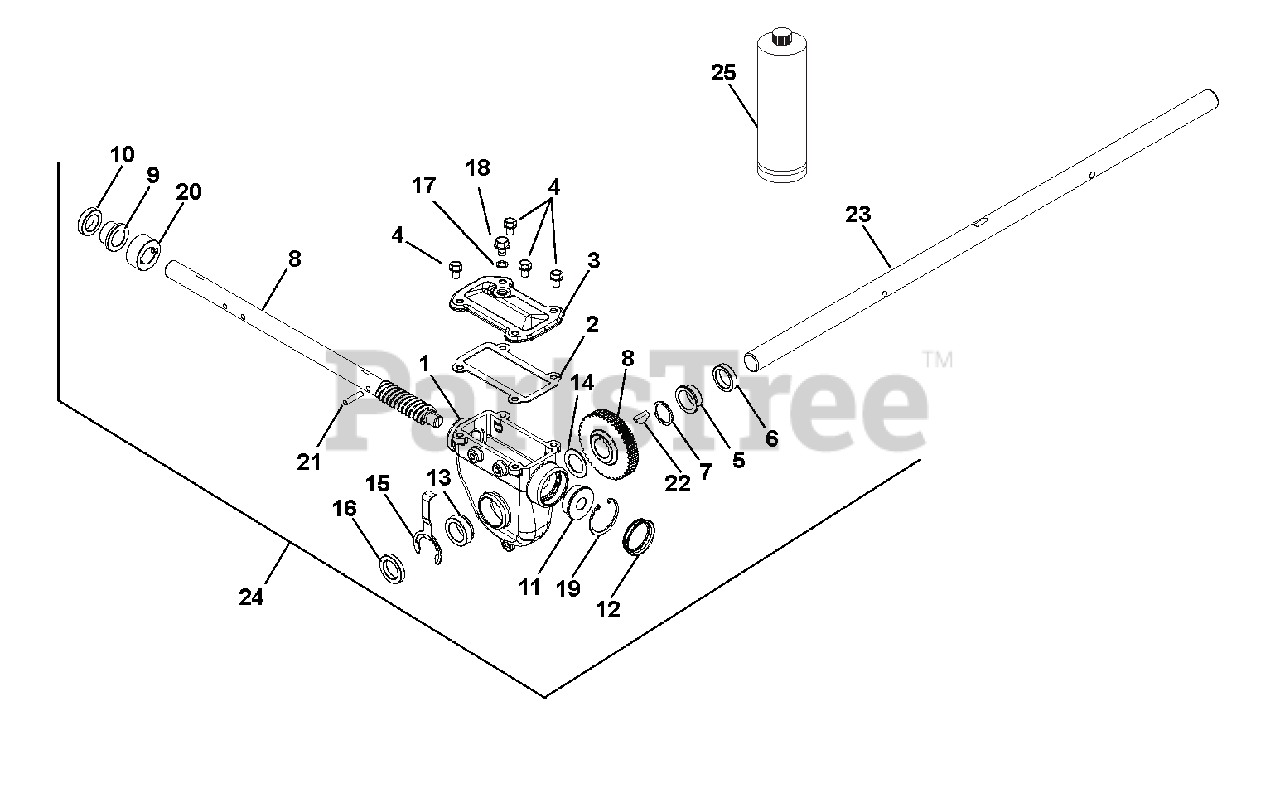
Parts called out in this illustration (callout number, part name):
1	GEARCASE, LARGE MACHINED
2	GASKET, TOP - LARGE GEARCASE
3	COVER, TOP - LARGE IRON
4	BOLT, SEMS .31-18X.50 GR5 YWZC
5	BSHG-FLG 1.006X1.128X.555X1.45
6	SEAL-OIL .999X1.375X.312 TBC29
7	WSHR-FL-STL 1.010X1.505X.062YZ
8	ASSY, WORM SHAFT & GEAR
9	BSHG-FLG .879X1.128X.75X1.45
10	SEAL-OIL .873X1.375X.312 TBC29
11	BSHG-FLG .628X1.503X.58X1.725
12	COVER, GEAR CASE 1.75"
13	BSHG-FLG LARGE, RIGHT
14	WSHR-FL-STL 1.010X1.250X.068YZ
15	BUSHING RETAINER, LARGE
16	SEAL-OIL .999X1.500X.250 TBC29
17	WSHR-BND-SEAL .38X.75X.11 GALV
18	@SCR-ROLOK .38-16X.50 HWH YWZC
19	RG-RTNG-INT 1.750X.062
20	THRUST COLLAR, .875"ID SLIPFIT
21	PIN-STR .250X1.12 6150
22	KEY-WDRF .25X.875 HRD #A
23	SHAFT, RAKE-28"
24	GEAR CASE, 28" IRON PRO TOP-LD
25	ARIENS L3 LUBE, 8 OZ BOTTLE
